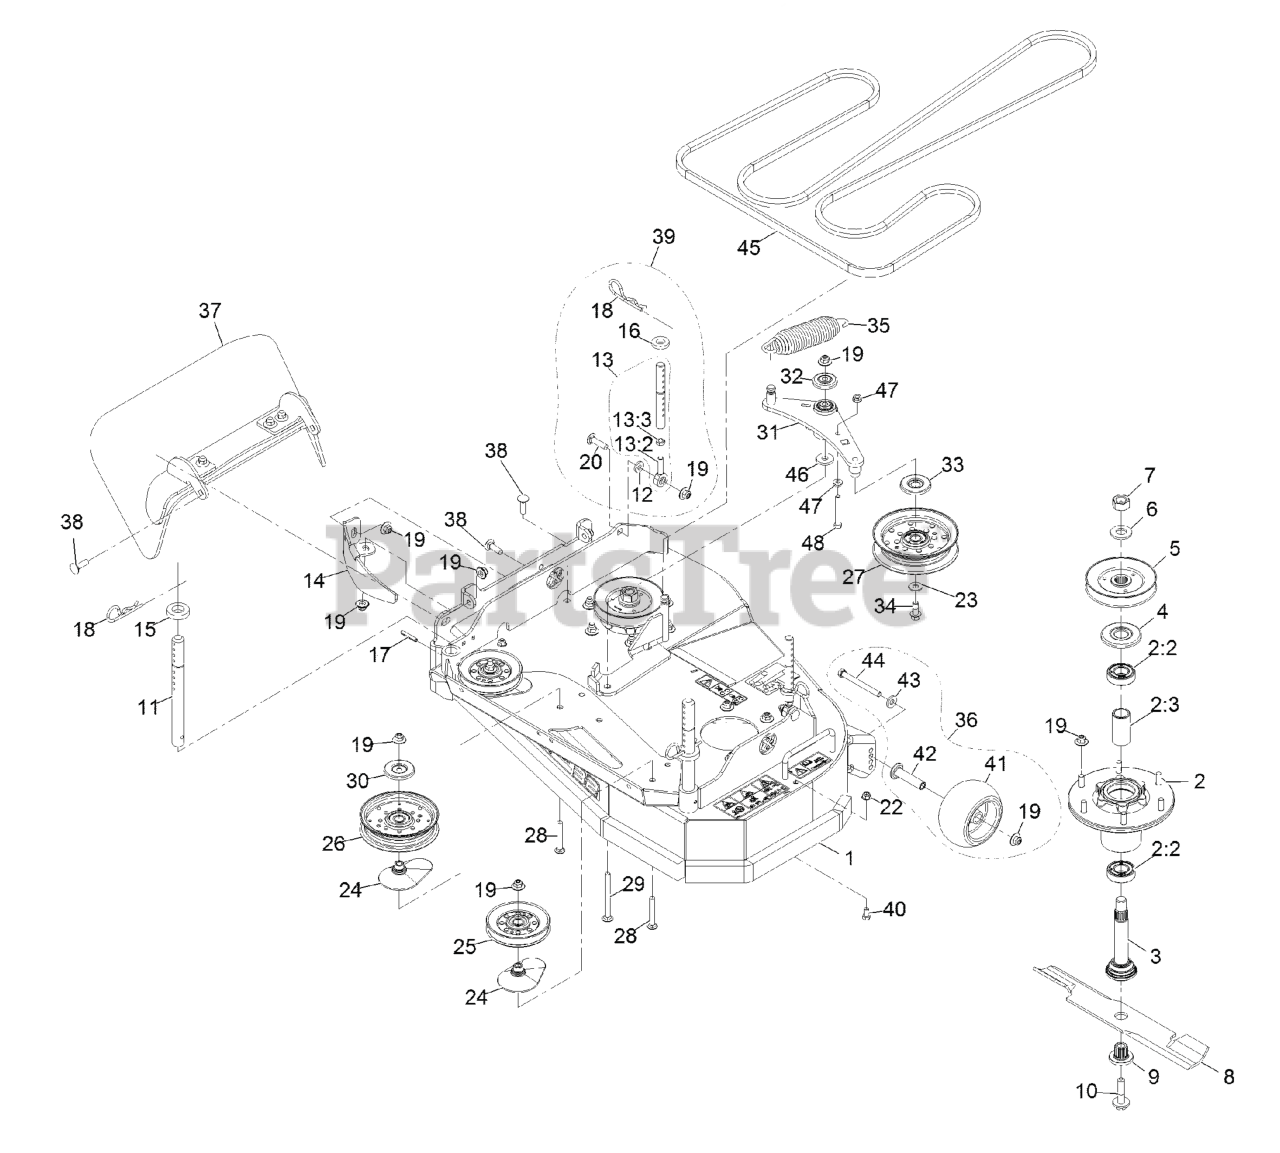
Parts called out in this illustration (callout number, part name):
1	ASM-DECK DECALS 32
2	ASM-CUTTER HSG WITH BEARINGS
2:2	BEARING-BALL
2:3	SPACER-BEARING
3	ASM-SPINDLE AND SEAL
4	GUARD,BEARING TOP .989
5	SHEAVE-BLADE DRIVE
7	NUT-HEX
9	BUSHING,SPLINED
10	SCREW,SEMS 1/2-20 X 2.19
11	ROD, DECK SUPPORT
13	ASM, Support Link
13:2	BALLJOINT
13:3	NUT-HJ
14	BAFFLE, DOGLEG
15	SPACER-DECK SUPPORT
18	PIN-CUT HEIGHT
19	Nut-Nyloc 3/8-16 Flg
20	SCREW-CARR
22	NUT-HF, NI
23	WASHER-FLAT
24	SPACER-PULLEY
25	Idler - V 4.13 Eod-A
26	PULLEY-IDLER, FLAT
27	IDLER-PULLEY, FLAT
28	SCREW-CARR
29	SCREW-CARR
30	SHIELD-DUST
31	ASM.-ARM, IDLER
32	GUARD-TOP
33	SHIELD-GUARD, DUST
34	SCREW-HFH
35	SPRING-EXTENSION
36	KIT-ANTISCALP ROLLER
37	RUBBER DEFLECTOR ASM
38	BOLT-CARR
39	KIT-SUPPORT LINK SVC
40	SCREW-HH
41	ROLLER-SCALP, ANTI
42	AXLE, ROLLER
43	WASHER-BELLEVILLE
44	SCREW-HH 3/8-16 X 3 3/4 GR 8
48	SCREW-HH
